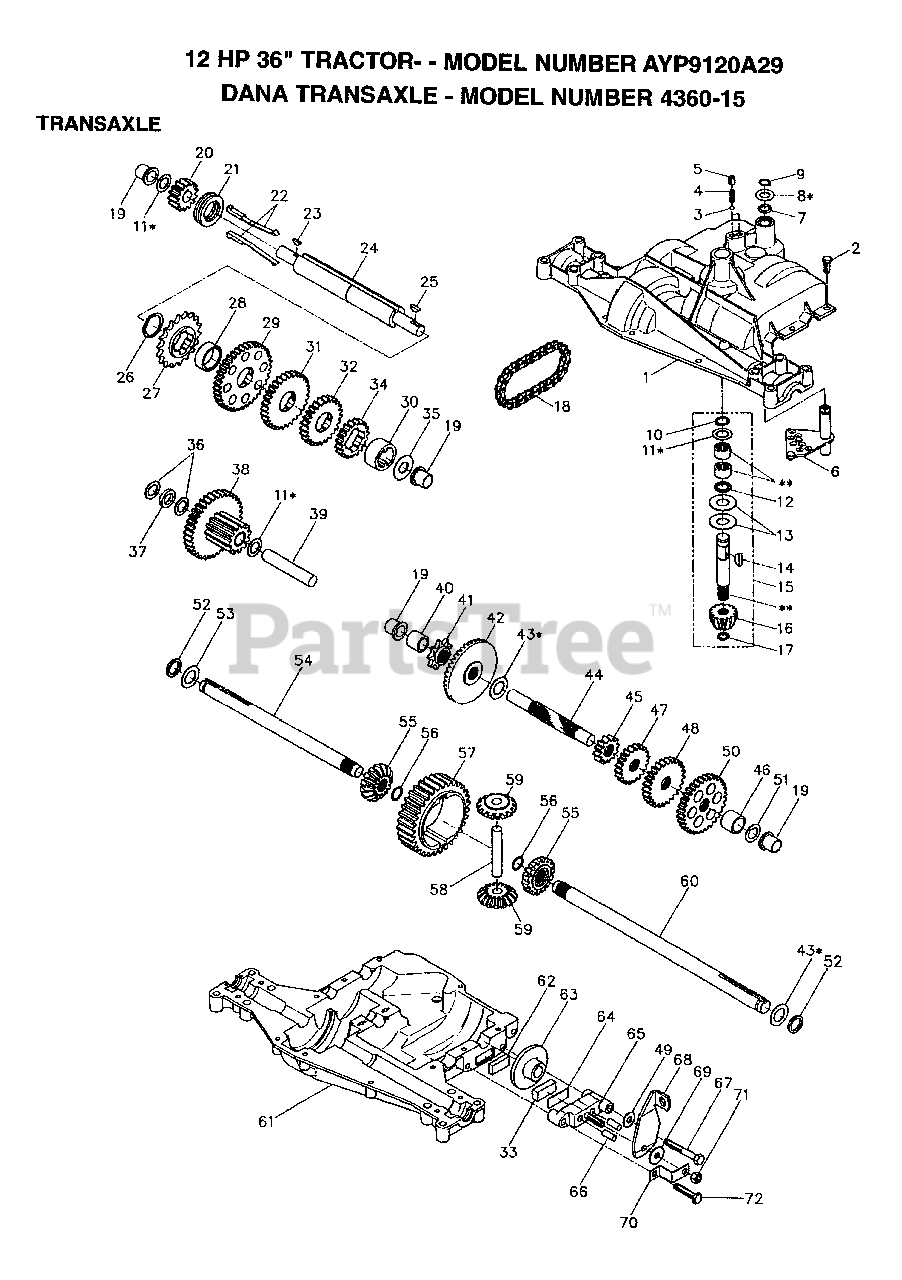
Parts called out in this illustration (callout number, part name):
3	"DETENT, BALL(68003)"
4	"SPRING, DETENT LT"
5	"SCREW, SET LT"
7	ORING T
9	RETAINING RING LT
10	RETAINING RING LT
11	WASHER
12	O-RING T
13	WASHER T
14	WOODRUFF KEY
15	IMPUT KIT T
16	PINION 14T T
17	"RING,RETAINING LT"
18	"CHAIN,24 PTCH LT"
19	BEARING.FLNG.5510
22	KEY T
25	WOODRUFF KEY
26	"RING,RETAINING LT"
27	SPROCKET 18T T
28	SPACER YT
29	KIT.GEAR.12/37TH
32	GEAR 25T LT
33	PUCK T
35	"WASHER, PLAIN LT"
36	WASHER 025
37	SPACER
38	ASSM GEAR COMB
39	SHAFT IDLER T
40	SPACER T
41	SPROCKET 9T LT
43	WASHER LT
44	SHAFT T
48	"GEAR, SPUR 25T LT"
49	WASHER T
50	"GEAR, SPUR 31T LT"
51	WASHER 060
53	WASHER 062
55	GEAR 15T T
56	"RING,RETAINING LT"
58	SHAFT T
59	GEAR 1ST T
62	PUCK T
63	BRAKE DISC. T
64	SPACER LT
66	PIN T
67	SCREW T
68	LEVER ACTUATOR
69	WASHER LT
71	NUT.LOCK.5/16-24
72	"SCREW, TAPPING LT"
